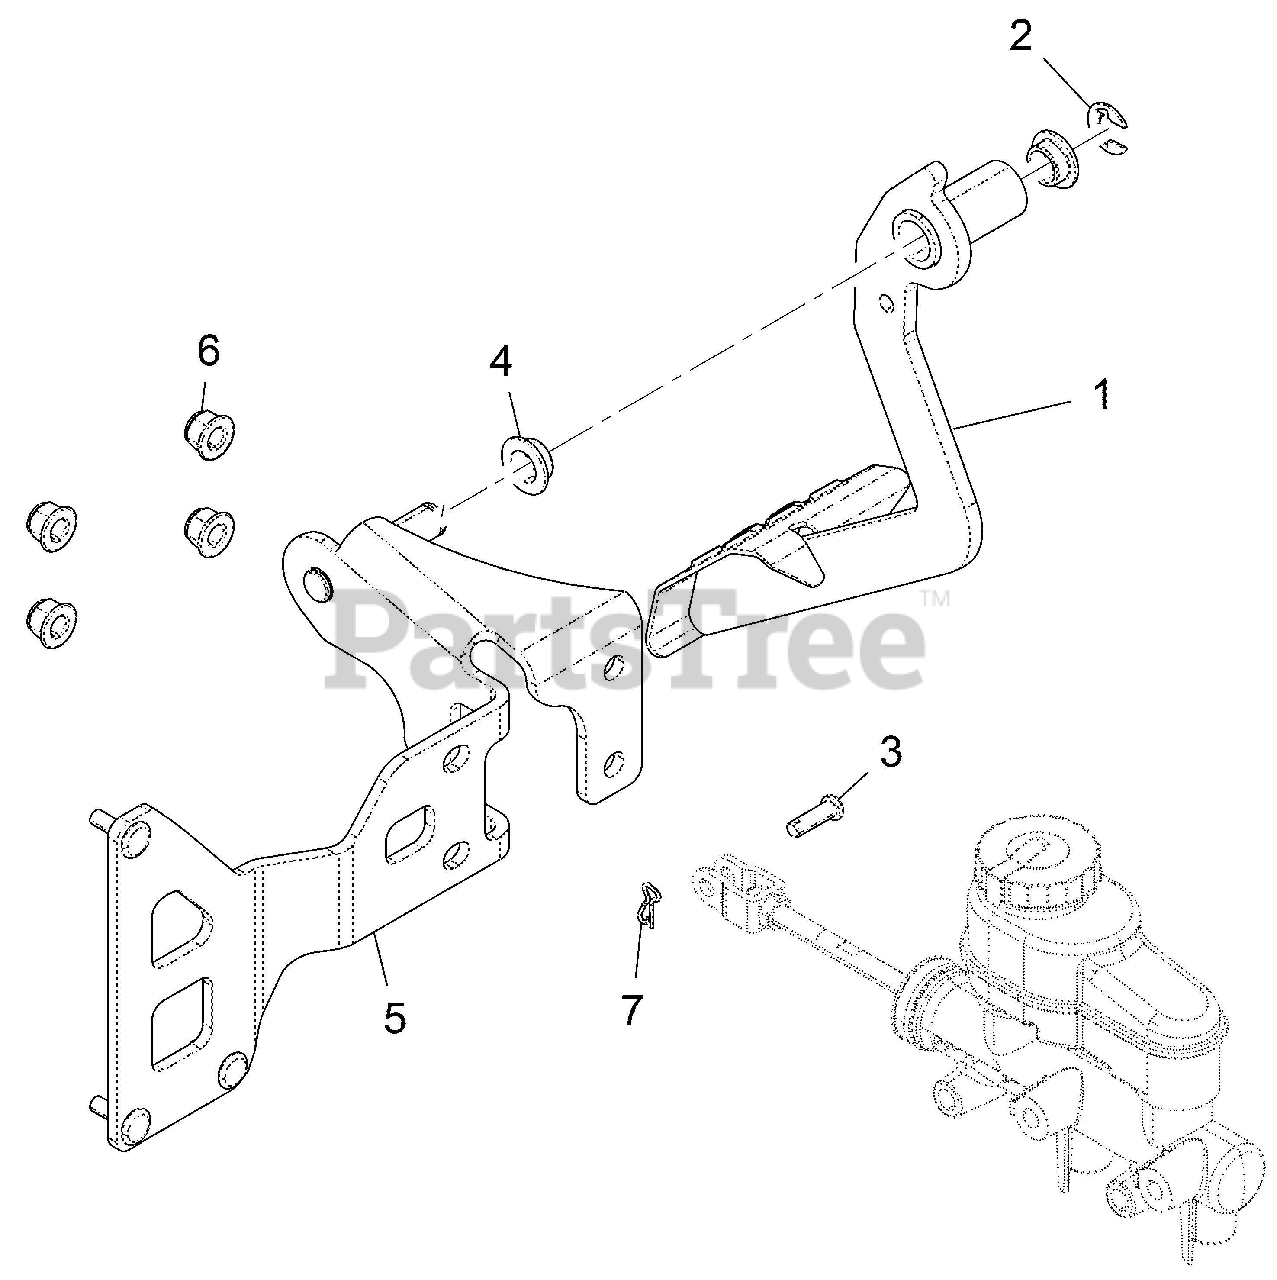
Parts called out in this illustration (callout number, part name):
1	PEDAL, BRAKE, MATTE BLACK
3	PIN-CLEVIS, 1/4 X 3/4 -Y
4	BUSHING-PEDAL PIVOT
5	MOUNT, PEDAL, BLACK
6	NUT-M8X1.25,FLG,NYLOC-OLIVE D
7	PIN-CLIP,14MM
